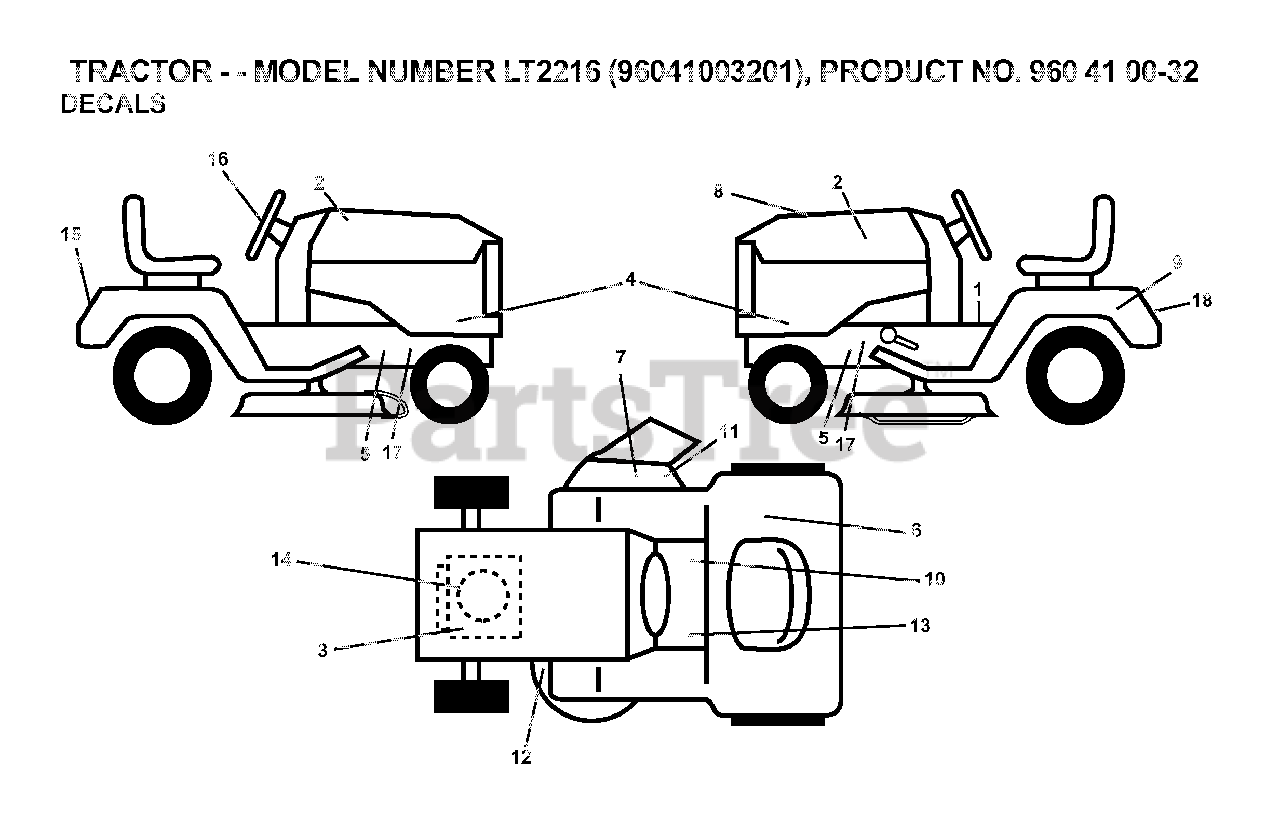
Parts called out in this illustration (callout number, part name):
7	DECAL.INTERNATIONL.CUTFINGER
9	DECAL BTRY SYMBOLS
10	DECAL PARK BRAKE
11	DECAL, DEFLECT WARNING
12	DECAL.V-BELT.SCHEMATIC.36/38/9
